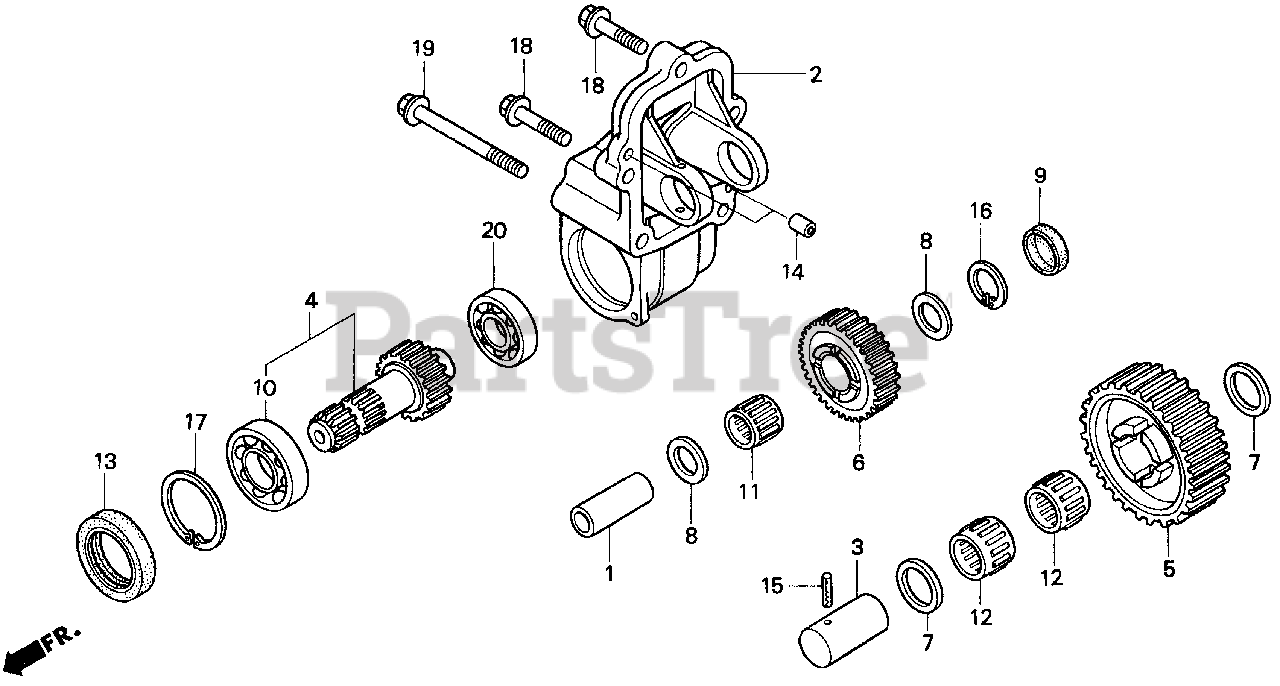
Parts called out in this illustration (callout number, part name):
1	PIN, PISTON
2	COVER, MIDDLE P.T.O.
3	SHAFT, MIDDLE P.T.O. IDLE
4	SHAFT, MIDDLE P.T.O.
5	GEAR A, MIDDLE P.T.O. IDLE (34T)
6	GEAR B, MIDDLE P.T.O. IDLE (23T)
7	WASHER, THRUST (22X39X2)
8	WASHER (18MM)
9	PLUG, SEALING (19X5)
10	BEARING, RADIAL BALL (S6205) (KOYO)
11	BEARING, NEEDLE (18X25X22)
12	BEARING, NEEDLE (22X29X16)
13	OIL SEAL (25X52X8)
14	PIN C, DOWEL (8X14)
15	PIN, SPRING (5X36)
16	CIRCLIP (INNER) (18MM)
17	CIRCLIP (INNER) (52MM)
18	BOLT, FLANGE (10X40)
19	BOLT, FLANGE (10X85)
20	BEARING, RADIAL BALL (6204)
